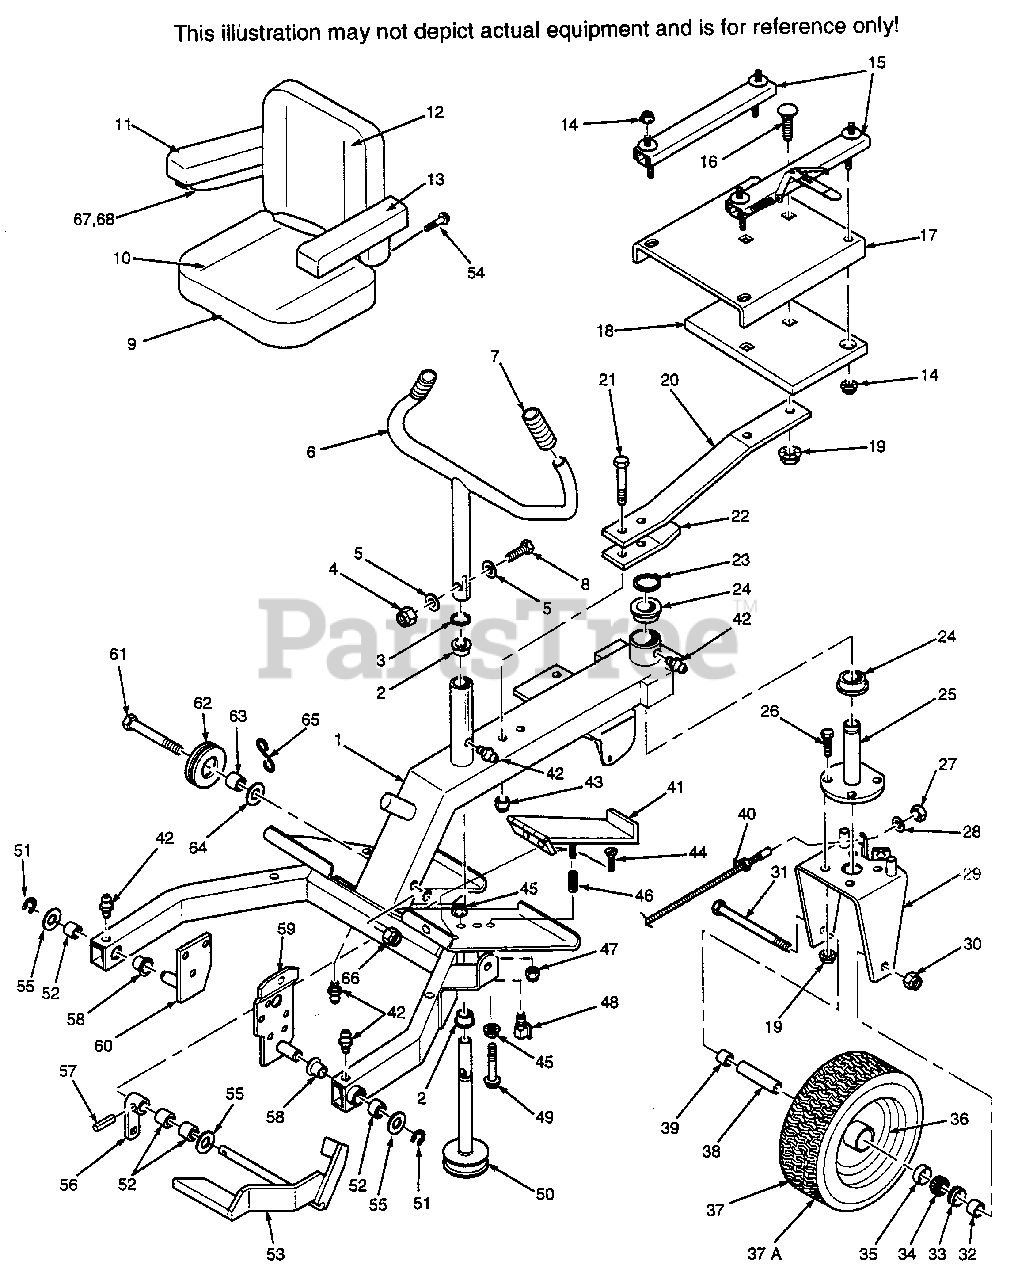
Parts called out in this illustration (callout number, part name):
1	STEERING FRAME(INCLUDES BSHGS AND FITTINGS)
2	BRONZE BUSHING
3	RETAINING RING, 7/8 EXTERNAL
4	HEX NUT, ELASTIC STOP 5/16-18
5	FLAT WASHER, 5/16(3/8 X 7/8 X 13 GA.)
6	STEERING HANDLE(INCLUDES ITEM 7)
7	GRIP
8	BOLT, HEX HD., 5/16-18 X 1-3/4"
9	SEAT ASSY.(INCLUDES ITEMS 10 THRU 15 & 67)
10	CUSHION ASSEMBLY
11	ARM PAD - R.H.
12	SEAT BACK CUSION
13	ARM PAD L.H.
14	SERR. FL. HH. NUT, 5/16-18
15	SEAT ADJUSTER TRACK
16	BOLT, RDHD CARR. 3/8-16 X 1-1/2
17	SEAT PLATE
18	BALLAST, SEAT MOUNT(72" CUTTER DECK ONLY)
19	SERR FL. HEX NUT, 3/8-16
20	SEAT SPRING
21	BOLT, HEX HD., 7-16-14 X 3-1/2
22	REINFORCEMENT, SEAT SPRING
23	RETAINING RING, 1-1/8" EXTERNAL
24	BRONZE BUSHING
25	REAR WHEEL PIVOT
26	BOLT, HEX HD., 3/8-16 X 1-1/4
28	LOCK WASHER, 3/8 INTERNAL TOOTH
29	REAR WHEEL YOKE
30	HEX ELASTIC STOP NUT, 5/8-11
31	BOLT, HEX HD. 5/8-11 X 9"
32	SPACER, REAR WHEEL, SHORT
33	SEAL, GREASE
34	BEAING CONE
35	BEARING CUP
36	RIM ONLY
37	REAR WHEEL ASSY.(INCLUDES ITEMS 33-36, 37A)
37A	TIRE ONLY
38	SLEEVE, REAR WHEEL
39	SPACER, REAR WHEEL
40	CABLE, STEERING(INCLUDES HARDWARE)
41	PEDAL, FOOT SAFETY SWITCH
42	GREASE FITTING
43	HEX ELASTIC STP NUT, 7/16-14
44	SCREW, SLOTTED FLAT HD #10-32 X 3/4"
45	SERR. FL. HEX NUT, 1/4-20
46	SPRING, FOOT SAFETY SWITCH
47	HEX NUT, ELASTIC STOP LOCK, 1/4-20
48	SWITCH, FOOT SAFETY
49	BOLT, HEX HD., 1/4-20 X 1-3/4
50	STEERING SHAFT
51	RETAINING RING 3/4 EXT. "E"
52	BRONZE BUSHING, OILLUBE
53	FOOT PEDAL
54	SCREW W/WASHER, 1/4-20 X .75
55	FLAT WASHER, 3/4 X 1-1/4 X 16 GA.
56	FOOT PEDAL ARM
57	PIN, DRIVE LOCK 3/16 X 1-1/4"
58	BRONZE BUSHING, OILLUBE
59	SULKY MTG. BRKT. L.H.
60	SULKY MTG. BRKT. R.H.
61	BOLT, HEX HD., 1/2-13 X 5-1/2"
62	PULLEY, WINCH CABLE
63	BRONZE BUSHING, OILLUBE
65	RETAINER, WINCH CABLE
67	ARMREST BRACKET, LEFT HAND
68	ARMREST BRACKET, RIGHT HAND
